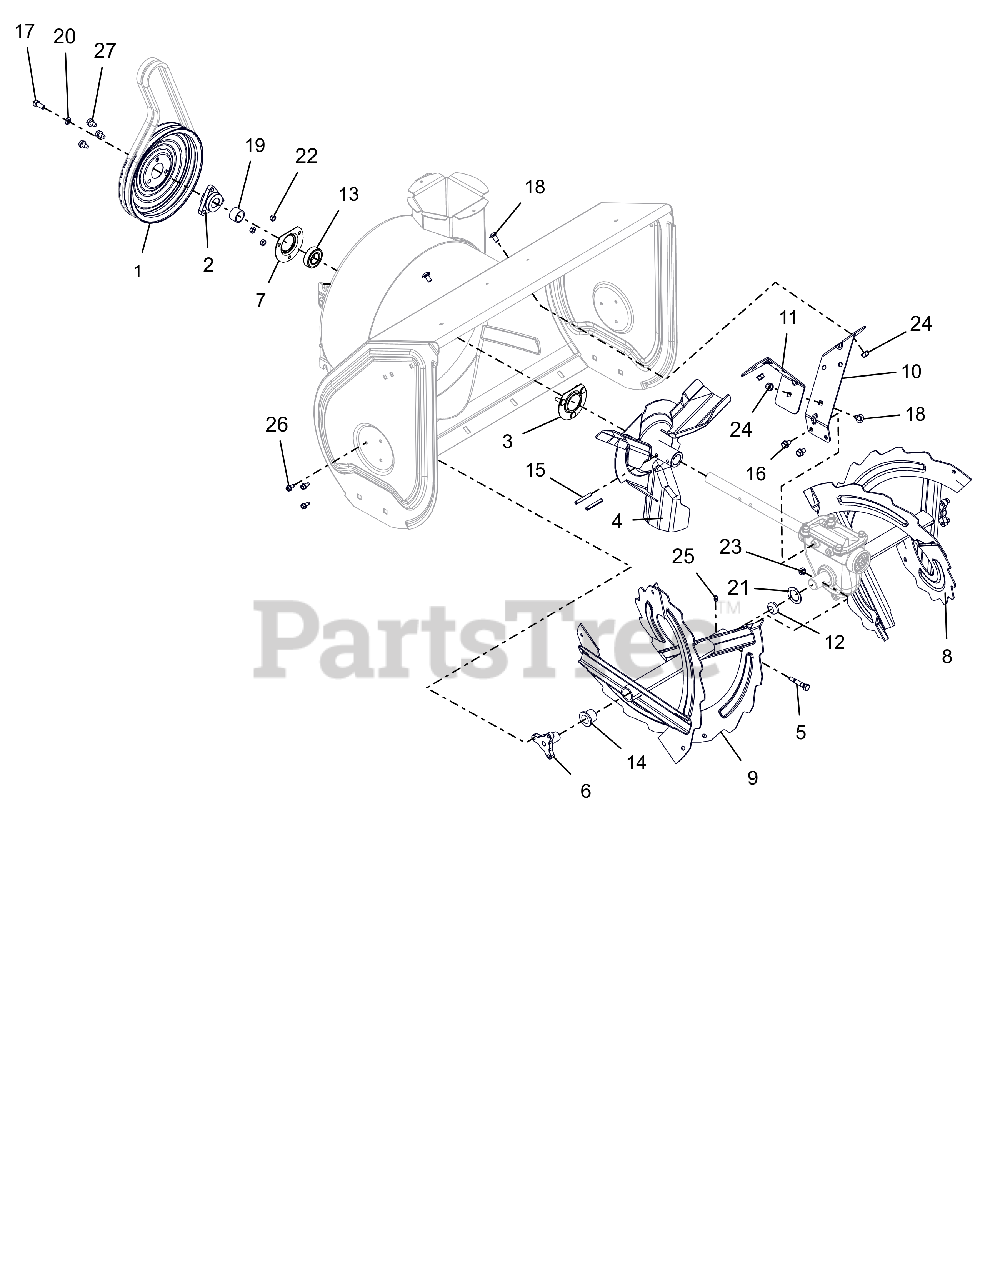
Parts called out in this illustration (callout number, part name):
1	PULLEY, SPIN FORM DUAL GROOVE
2	PULLEY HUB, D-BORE .87 DELUXE
3	BEARING FLANGE
4	IMPELLER, 3 BLADE-14"
5	SHEAR BOLT SERVICE ASSEMBLY
6	SUPPORT, RAKE BUSHING
7	BEARING FLANGE
8	RAKE, LH W/ZERK - 28"
9	RAKE, RH W/ZERK - 28"
10	BRACKET, GEARCASE SUPPORT - LH
11	BRACKET, GEARCASE SUPPORT - RH
12	PLUG, RAKE TUBE
13	BRG-BALL .876X1.75X.50 RSTFP
14	BSHG-FLG, NY.778 ID X 1.018 OD
15	PIN-ROLL .250X1.75
16	BLT, SEMS .31-18X.50 G5 ZCC
17	BLT, HEX .31-24X.750 G5 ZCC
18	BLT-RDHDSQSHNK.31-18X.62 YZ-LK
19	BSHG,SPCR .895X1.065X.693
20	WSHR, LK-HVY .312X.097 ZCC
21	WSHR, FLT 1.010X1.505X.062 ZCC
22	NUT,LK-CTR .25-20 GA ZCC
23	NUT,LK-CTR .31-18 GA ZCC
24	NUT-LK-TOP-FLG .312-18 GF ZCC
25	ZERK,FITTING .25X.125 DRIVE IN
26	SCR-TAP .25-20X.50 HWH ZCC
27	SCR,TAP .312-18X.50 HWH TR ZCC
